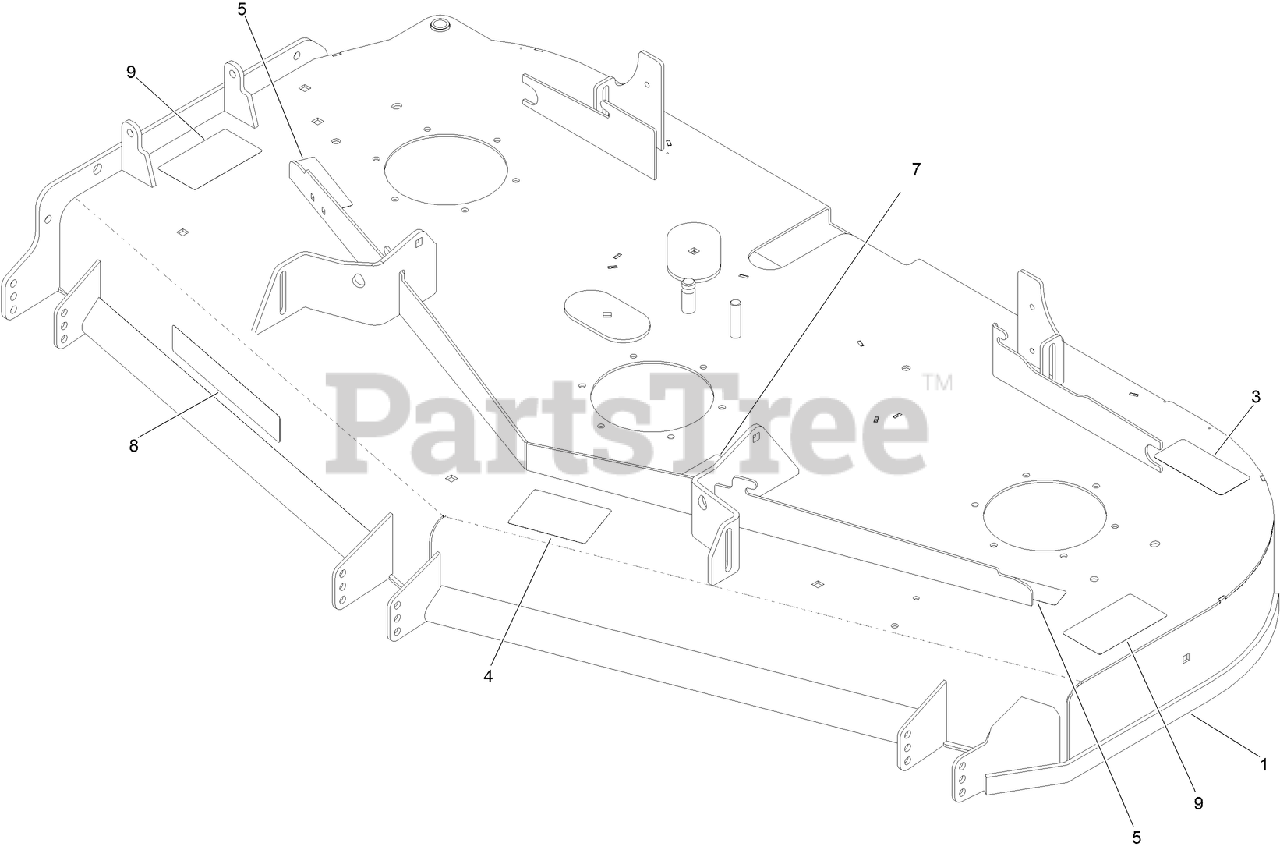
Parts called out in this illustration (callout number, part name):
1	DECK DECAL ASM
3	DECAL-TORQUE, BLADE BOLT
4	DECAL-SCALP, ANTI
5	DECAL-COVER, MISSING
7	DECAL-ROUTING, BELT
9	DECAL-DANGER
